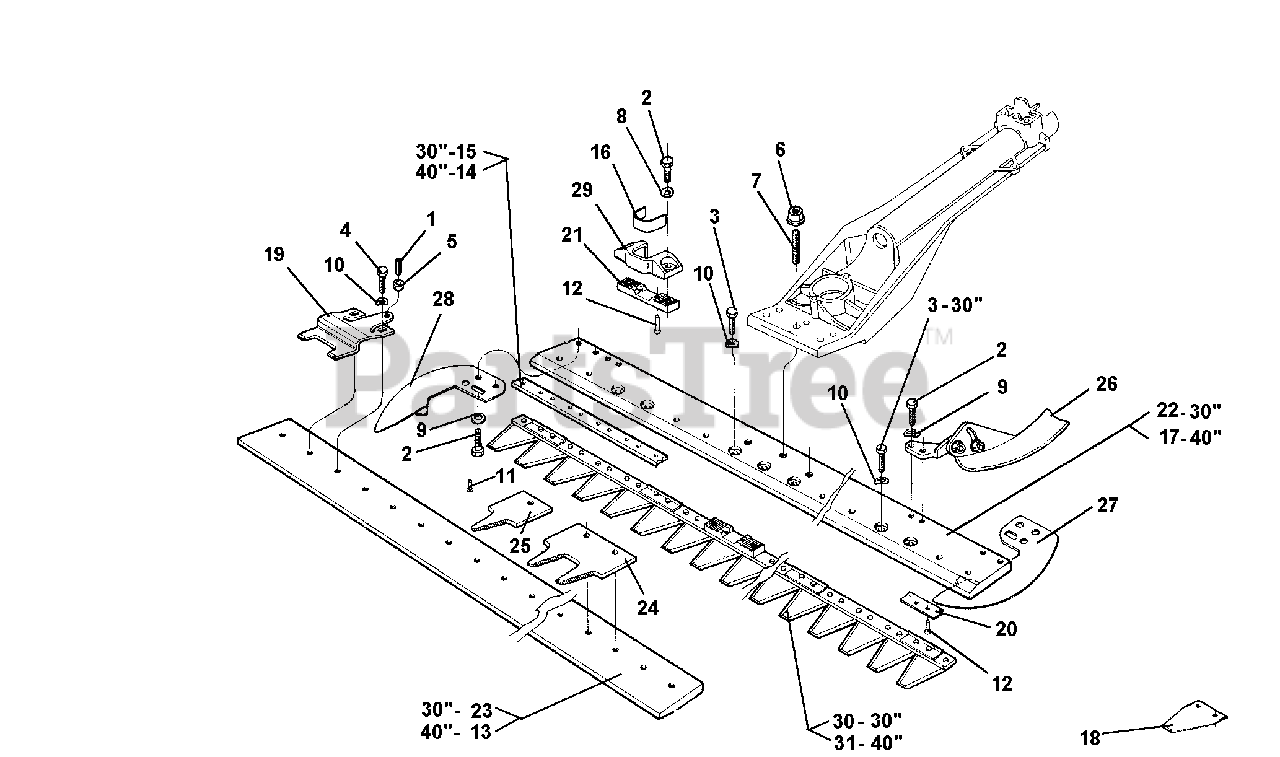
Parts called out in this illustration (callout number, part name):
1	SCREW M8 X 14
2	SCREW M8 X 16
3	SCREW M8 X 25
4	SCREW TE M8 X 30
8	WASHER, FLAT 8.4
9	SUPER WASHER 8 DIN 6796
10	WASHER, LOCK 8.4
11	RIVET 5.3 X 14
12	RIVET TSV 5.3 X 18
13	SLIDE FOR COMBO BAR 1.00 MT
14	BLADE STRIP
15	BLADE STRIP
17	CENTER, CUTTER BAR COMBO 1 M
18	SECTION F. NARROW SCORED BLADE
19	BLADE HOLDER
20	PLATE FOR CLEANING
21	BLADE COUPLING PLATE
22	CENTRAL BAR 0.80 MT.
24	DOUBLE FINGER
25	SINGLE FINGER
26	SKID, INTERMEDIATE
27	L.H. PROTECTION COMBO CUTTER
28	R.H. PROTECTION COMBO CUTTER
29	BLADE COUPLING
30	SMOOTH BLADE WITH COUPLING
31	SCORED BLADE WITH COUPLING
